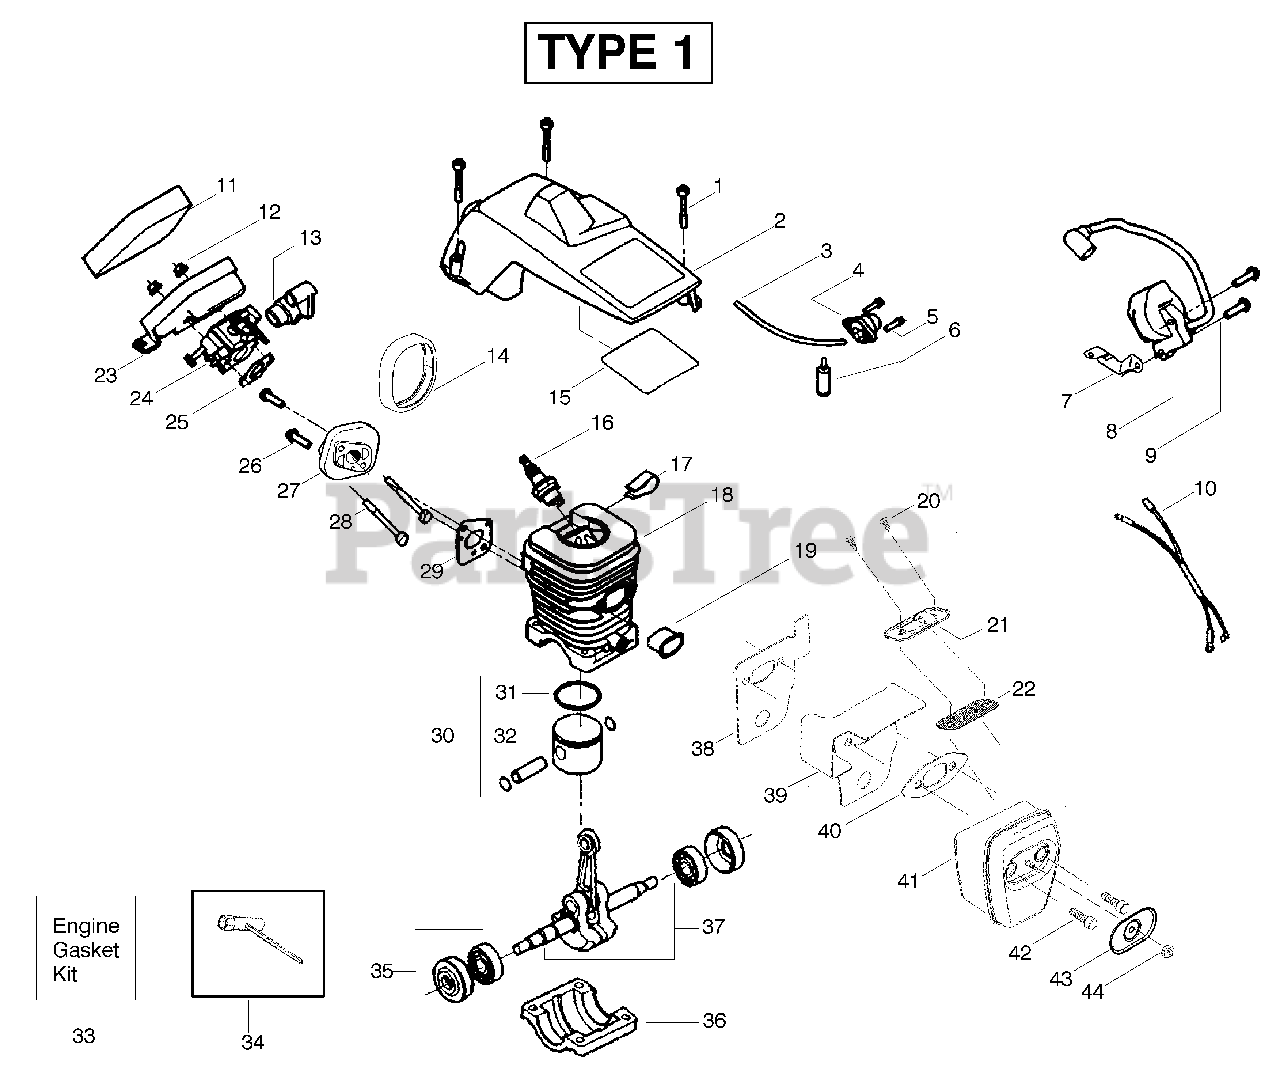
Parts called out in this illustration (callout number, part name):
2	Assy-Cylinder Shield
3	Kit-Fuel Line
4	Assy- Air Purge
6	Assy-Fuel Pick-Up
7	Strap-Ground
8	Ignition Module
10	Assy-Wire Harness
11	Foam- Air Filter
13	Grommet-Carb Adjust
14	Seal-Carb Adapter
15	Reflector-Heat
16	Spark Plug
17	Clip-High Tension Lead
18	Kit-Cylinder
19	Insulator-Heat
20	Screw-Outlet Cover
21	Cover - Outlet
22	Kit-Spark Arrestor
23	Air Filter Housing
24	Kit-Carburetor (WT-600)
24	Kit-Carburetor (WT-637)
25	Gasket-Carb.
27	Carb. Adapter
29	Gasket-Carb Adaptor
30	Kit-Piston
31	Ring-Piston
32	Retainer-Piston Pin
33	Kit-Engine Gasket
34	Bar Wrench
35	Assy-Seal & Bearing
36	Cap-Crankcase
37	Assy-Crankshaft
38	Backplate
39	Guide-Outlet
40	Gasket-Muffler
41	Assy-Muffler
42	Bolt-Muffler
43	Cover-Bolt
44	Nut-Brass
